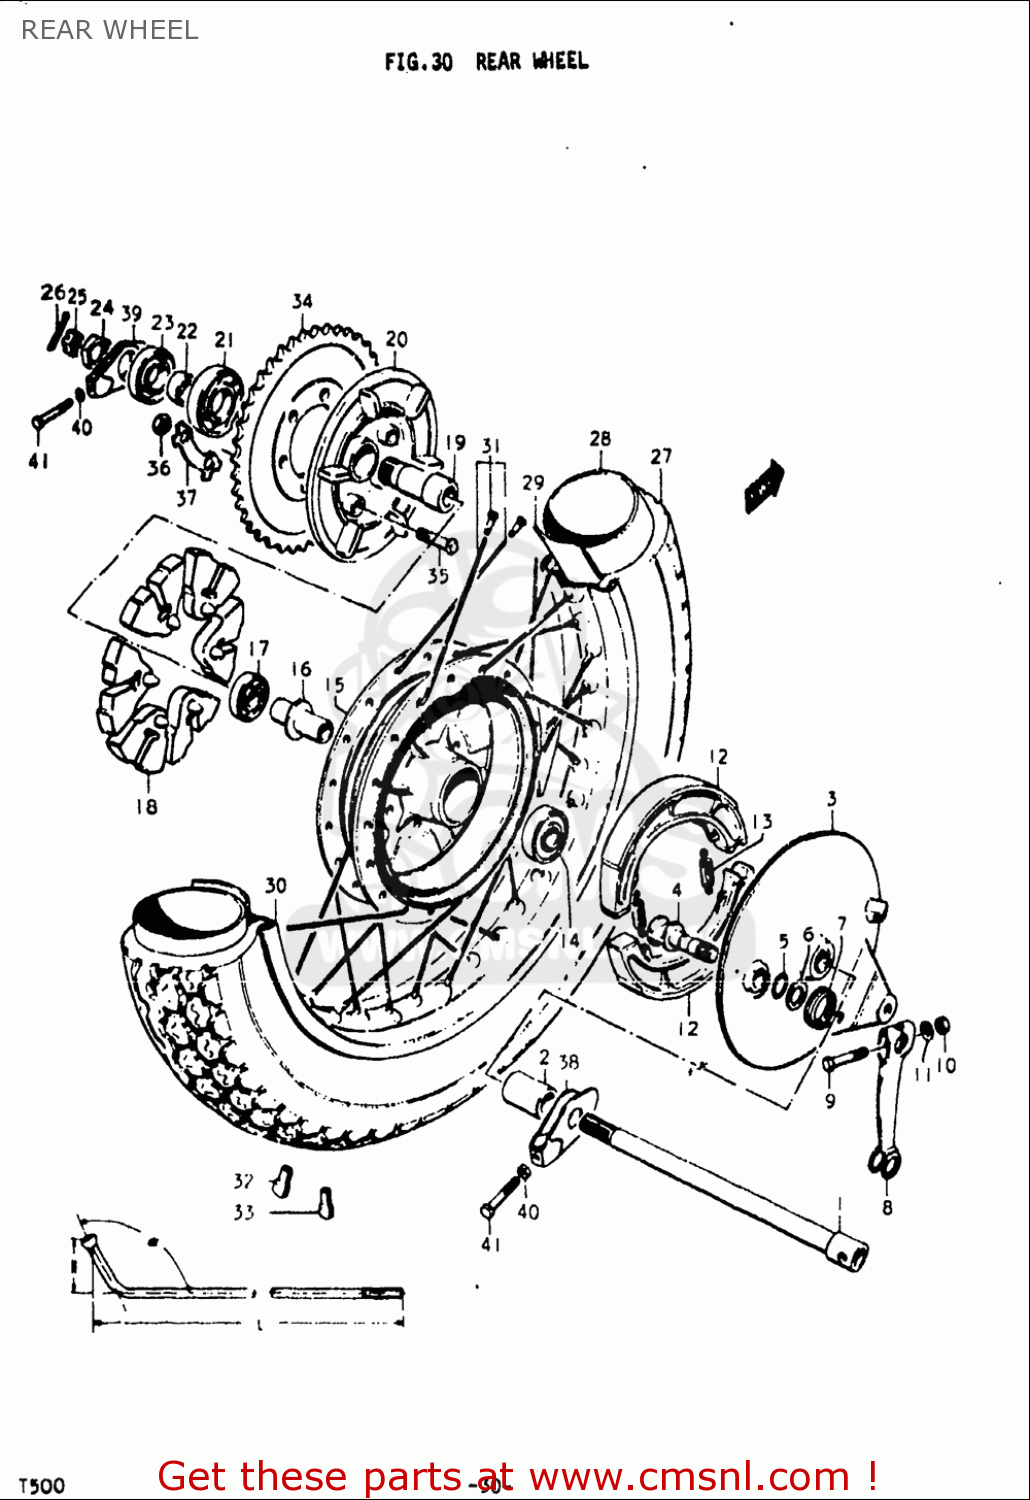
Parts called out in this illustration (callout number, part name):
1	AXLE,REAR
4	CAM,RR BRAKE
5	O RING(D:2.4,ID:14.8)
6	WASHER(15.5X24X1.6)
7	SPRING
9	BOLT
10	NUT
11	WASHER
12	SHOE SET,BRAKE (NAS)
13	SPRING,BRAKE SHOE
14	BEARING
16	SPACER
17	BEARING
18	ABSORBER,RR HUB SHOCK
21	BEARING(25X52X15)
22	SPACER (25X30.5X11.3)
23	SEAL,OIL(30.5X52X8)
24	NUT
25	NUT 16MM
26	PIN, COTTER
28	TUBE,INNER
29	PROTECTOR,INNER TUBE
31	SPOKE SET,RR WHEEL
32	BALANCER,WHEEL (B)
33	BALANCER,WHEEL (30G)
35	BOLT(10X35.5)
37	WASHER
39	ADJUSTER,CHAIN,L
40	NUT
41	BOLT(8X40)
